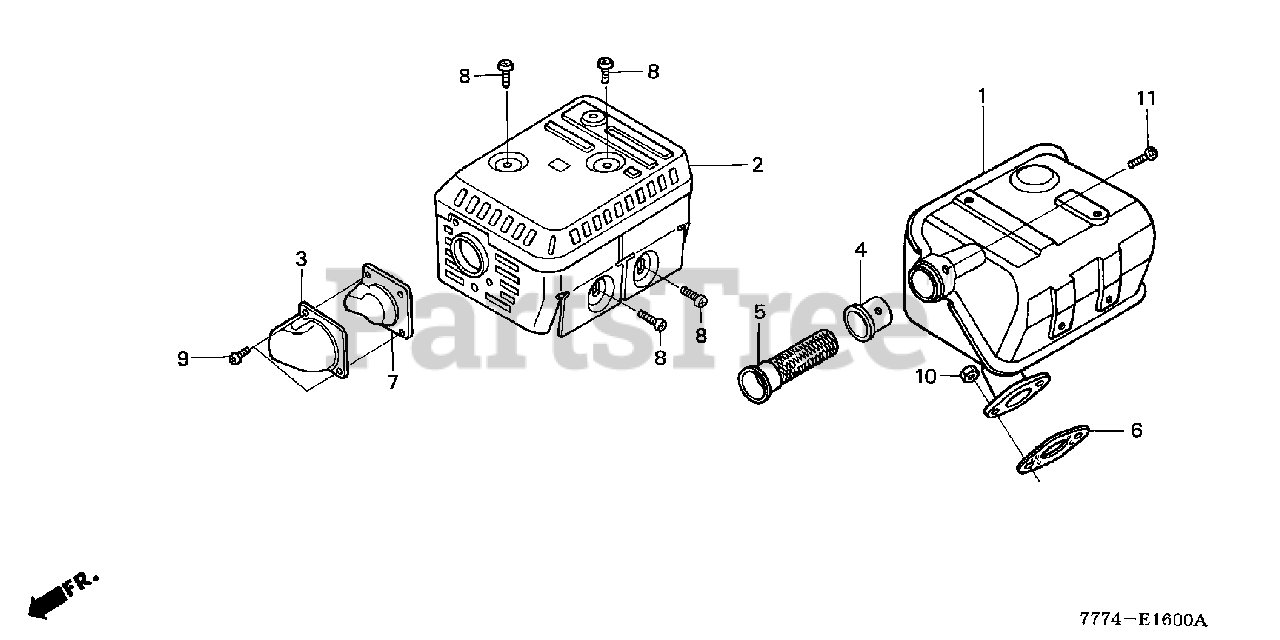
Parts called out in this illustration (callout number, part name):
1	MUFFLER
2	PROTECTOR, MUFFLER
3	DEFLECTOR, MUFFLER
4	PIPE, TAIL
5	ARRESTER, SPARK
6	GASKET, MUFFLER
7	GUIDE, MUFFLER
8	SCREW, TAPPING (5X8)
9	SCREW, TAPPING (4X6)
10	NUT, HEX. (8MM)
11	SCREW, TAPPING (5X8)
11	SCREW, TAPPING (4X6)
